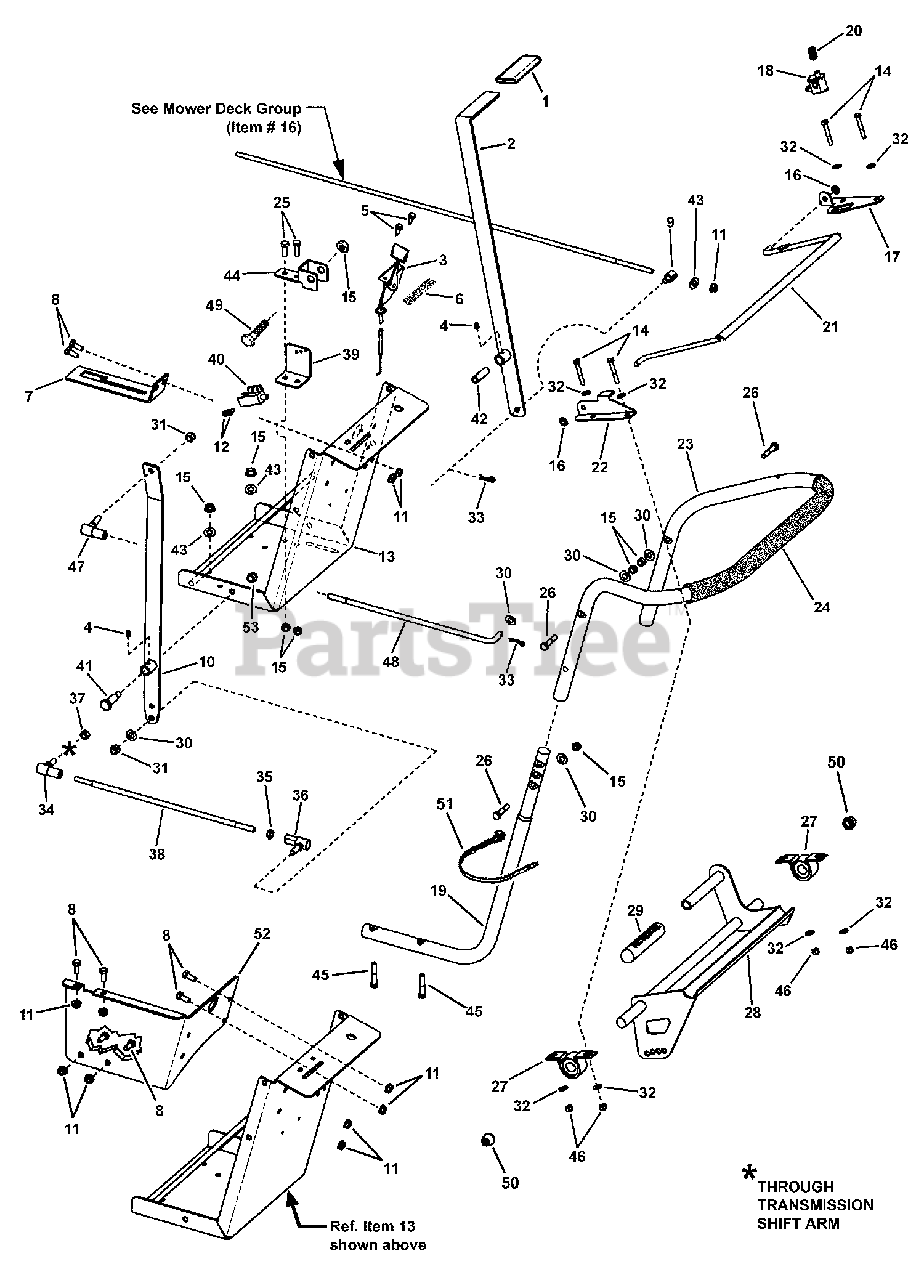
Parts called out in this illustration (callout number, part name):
1	GRIP, Handle
2	LEVER, Blade Clutch Engage (weldment)
3	THROTTLE CONTROL, Briggs 23"
3	THROTTLE CONTROL, Kawasaki 38"
3	THROTTLE CONTROL, Honda 34.6"
4	LUBE FITTING, 3/16" hole
5	SCREW, 1/4-20 x 3/4" Hex Washer Self-Tap
6	DECAL, Throttle, Brush Cutter
7	BRACKET, Blade Engage Lock
8	SCREW, 5/16-18 x 3/4" Hex Head Cap, GR 5
9	SWIVEL, Adjustable, 5/16-18 thread
10	LEVER, Transmission Drive (weldment)
11	NUT, 5/16-18 Hex Flange Lock, GR 5
12	SCREW, #10C x 1/2" Hex Head Self-Tap (Torx)
13	CONTROL DECK & DASH PANEL (weldment)
14	SCREW, 1/4-20 x 1-3/4" Hex Head Cap, GR 5
15	NUT 5/16-18 Hex Nyloc
16	RETAINER, 5/16" Bolt
17	BRACKET, Handle Pivot, RH
18	SWITCH, OPC, NC
19	HANDLE, Lower
20	SPRING, Safety Return
21	WELDMENT, Safety Bar
22	BRACKET, Safety Bar Pivot, LH
23	HANDLE, Upper
24	COVER, Foam
25	SCREW, 5/16-18 x 1" Hex Head Cap, GR 2
26	SCREW, 5/16-18 x 1-1/2" Hex Head Cap, GR 5
27	BEARING, 3/4 I.D.
28	WELDMENT, Drive Engagement Bar
29	GRIP, Reverse Handle
30	WASHER, 3/8 SAE Flat
31	NUT, 3/8-24 Hex Nyloc
32	WASHER, .28 x .63 x .06 Flat
33	HAIR PIN, #13
34	BALL JOINT, Type R (5/16-24 thread)
35	NUT, 3/8-24LH Hex Jam
36	BALL JOINT LH (3/8-24 LH thread)
37	NUT, 5/16-24 Hex Jam
38	ROD, Trans. Engage, Lower (3/8-24 & 5/16-24 threads)
39	BRACKET, Deck Safety Switch
40	SWITCH, Deck Safety
41	BOLT, 1/2 x 1-3/16 to 3/8-16 Shoulder
42	SPACER, Transmission, Express
43	WASHER, 5/16" SAE Flat
44	BRACKET, Clutch Engage Lever
45	SCREW, 5/16-18 x 1-3/4" Hex Head Cap, GR 5
46	NUT, 1/4-20 Hex Nyloc
47	BALL JOINT, 3/8-24 Thread
48	ROD, Trans. Engage, Upper (3/8-24 thread)
49	SCREW, 5/16-18 x 2-1/4" Hex Head Cap, GR 5
50	CAP, Push Plastic (for 3/4" dia. Rod)
51	CABLE TIE, 7"
52	BRACKET, Fuel Tank
53	NUT, 3/8-16 Hex Flange Lock
